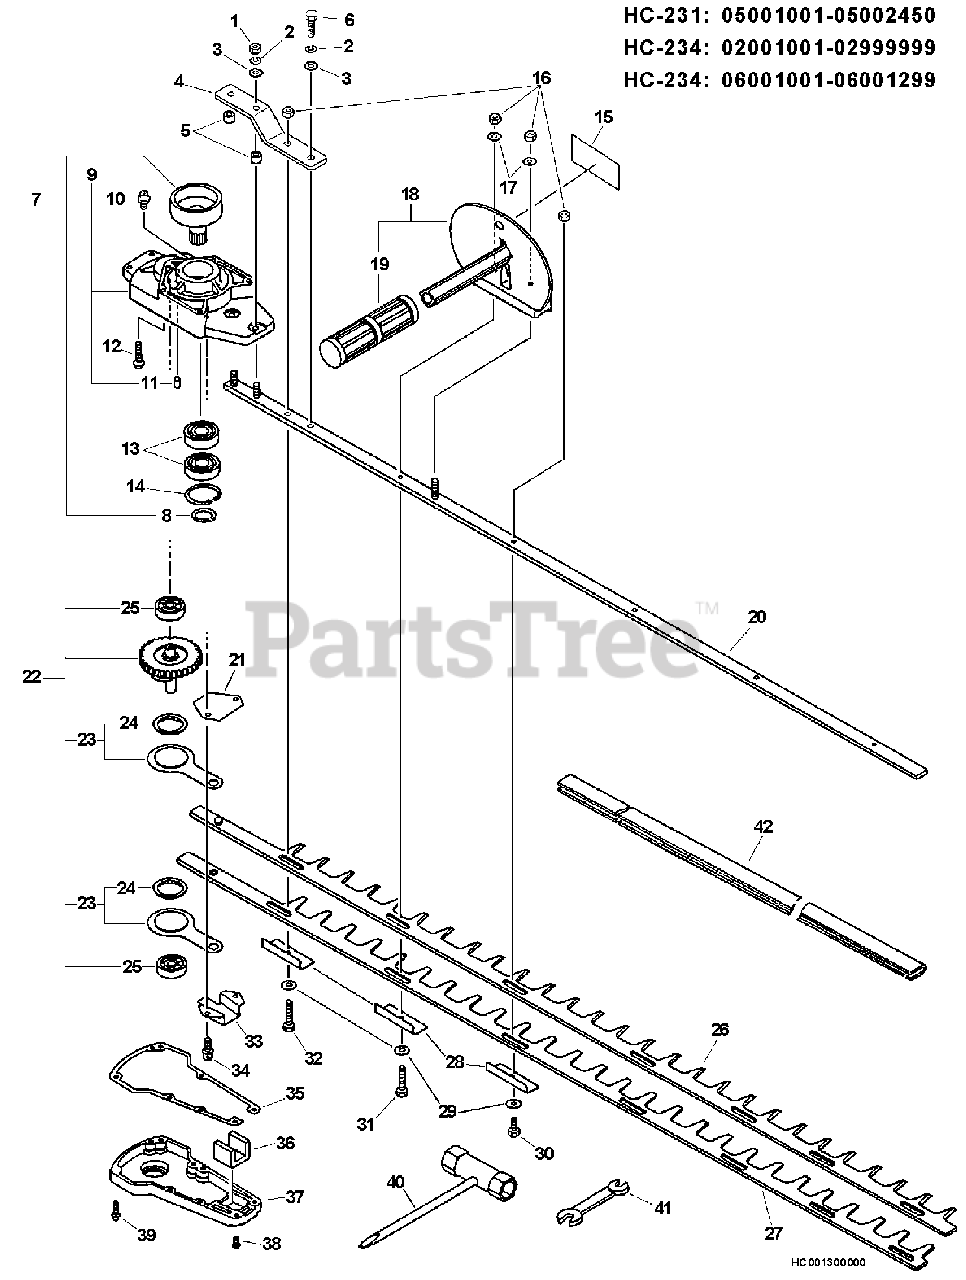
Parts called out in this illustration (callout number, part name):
1	NUT, HEX M6
2	WASHER, SPRING 6
3	WASHER 6.5×11.5×0.8
4	BRACKET, BLADE
6	BOLT 6×10
7	DRUM, CLUTCH
8	RING, RETAINING - 16
9	CASE, GEAR
10	FITTING, GREASE
11	PIN, LOCATING 4
12	BOLT 5×30
13	BEARING, BALL 6003
14	RING, SNAP 35
15	LABEL, CAUTION
17	WASHER 6.5×13×1
18	BRACKET ASSY
20	SUPPORT, BLADE
21	PLATE, GUIDE
22	GEAR ASSY
23	CONROD ASSY
24	BEARING, NEEDLE 30
25	BEARING, BALL 6200
26	BLADE - UPPER -- 40"
27	BLADE - LOWER -- 40"
28	INSULATOR
30	BOLT 6×22
31	BOLT 6×40
32	BOLT 6×25
33	GUIDE, BLADE
34	BOLT 4×16
35	GASKET, GEAR CASE
36	SEAL
37	LID, GEAR CASE
38	SCREW 4×14
39	SCREW 4×22
40	T-WRENCH 13×19×180
41	SPANNER 8×10
42	SCABBARD
